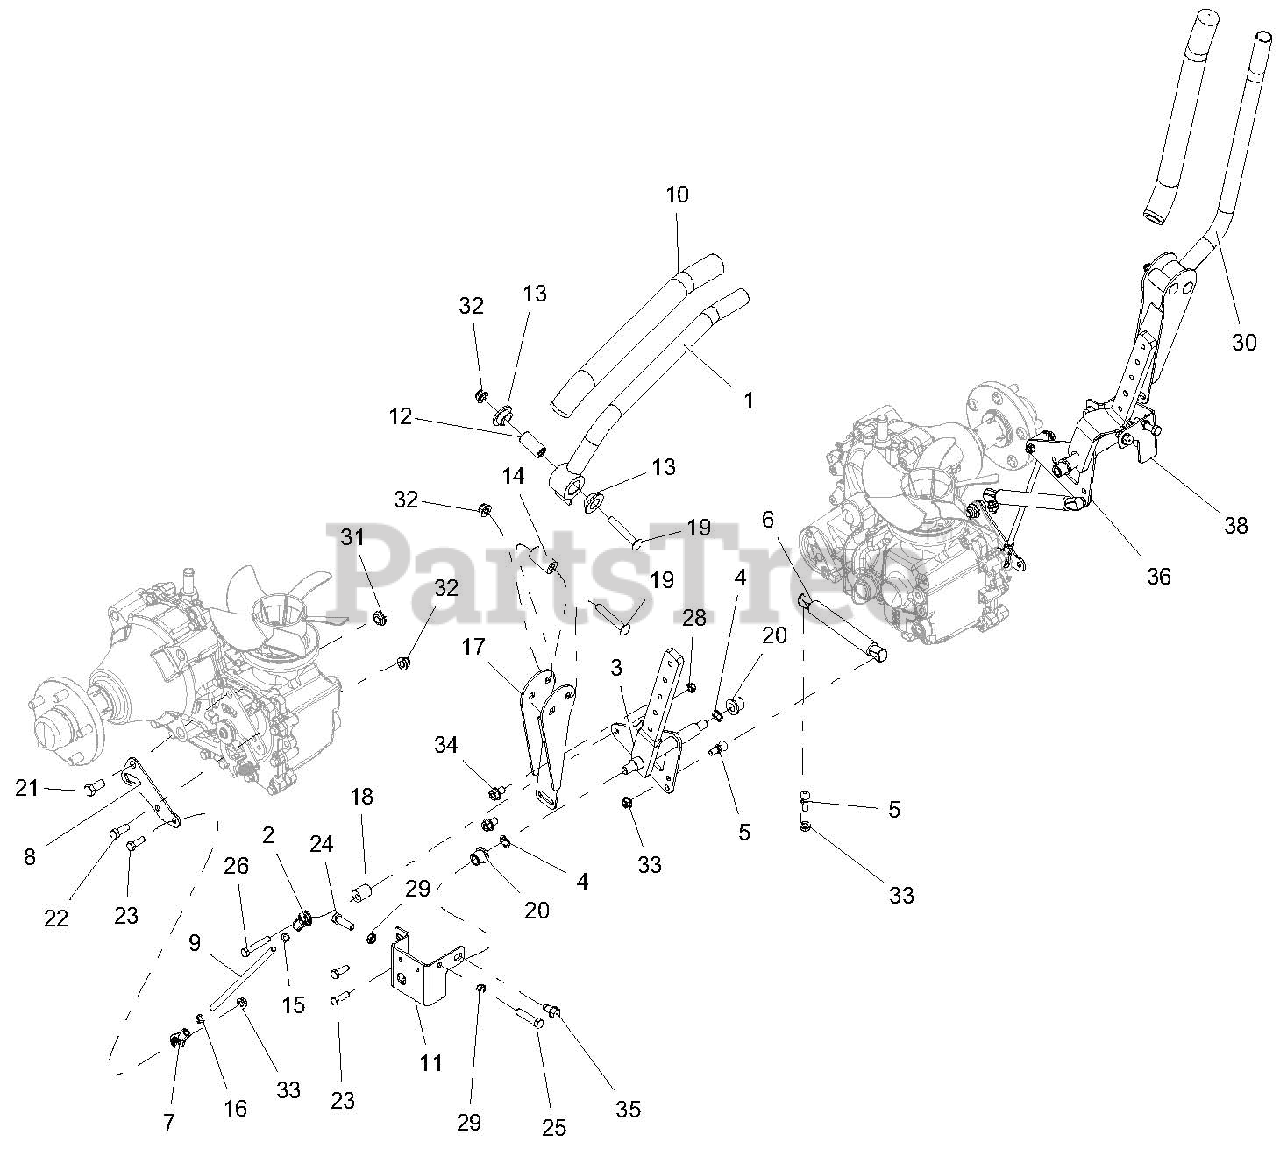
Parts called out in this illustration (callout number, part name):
1	WLDMT, RH CONTROL HANDLE
2	ALIGNABALL, 5/16 RH THREAD
3	WLDMT, RH LOWER CONTROL ARM
4	WAVE WASHER .531X.781X.125 FH
5	STUD-BALL
6	DAMPER,
7	ALIGNABALL, 5/16 LH THREAD
8	BRKT., CONTROL MTG-BLACK
9	ROD, STEERING
10	GRIP, HANDLEBAR
11	BRKT, RH CONTROL ARM STOP
12	SPCR, STEERING ARM
13	BSHG, FLANGE .762 X 1.48 X .44 NYLON
14	BSHG, ECCENTRIC .328 X .750 X 1.625
15	NUT-JAM
16	NUT, JAM -LH .31-24 YWZC
17	WLDMT, UPPER ADJUSTABLE CONTROL ARM
18	ECCENTRIC
19	BLT-RHDSSQNK .38-16X2.50 G5YZ
20	BHSG-FLG .500X.750X.750X.125
21	BLT-HEX .44-14X1.00 GR5 YWZC
22	BLT-HEX .38-16X1.00 GR5 YWZC
23	BLT-HEX .31-18X1.00 GR5 YWZC
24	BLT-HEX .38-16X1.25 GR5 YWZC
25	BLT-HEX .38-16X1.75 GR5 YWZC
26	BLT-HEX .31-18X2.00 GR5 YWZC
28	NUT-LK-CTR .31-18 YWZC
29	NUT, JAM .375-16 YWZC
30	WLDMT, LH CONTROL HANDLE
31	NUT-LK-NYL-FLG .44-14 YWZC
32	NUT-LK-NYL-FLG .38-16 YWZC
33	NUT, LK-TOP-FLG .312-18 YWZC
34	BLT-SERHFWH .38-16X.62 YWZC
35	SCR-TAP .38-16X.75 HWH TR YWZ
36	WLDMT, LH LOWER CONTROL ARM
38	BRKT, LH CONTROL ARM STOP
